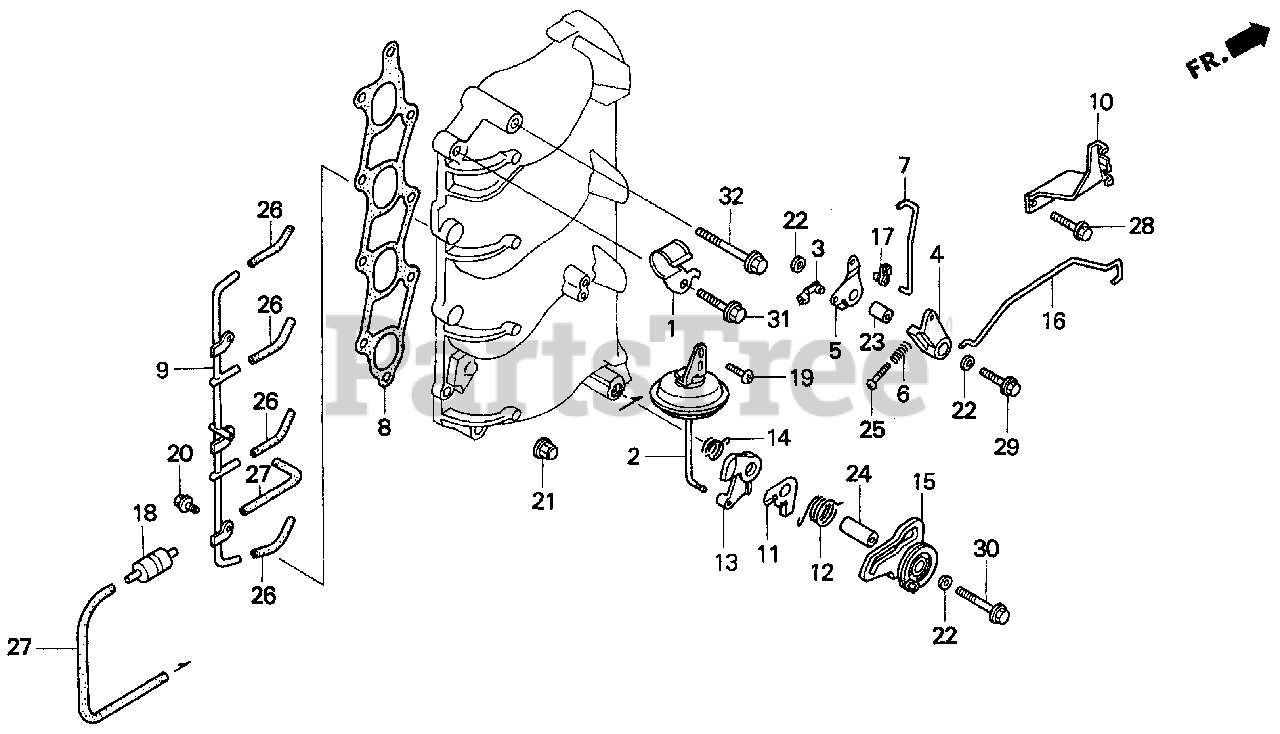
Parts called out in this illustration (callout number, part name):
1	CLAMP, TUBE
2	DIAPHRAGM ASSY.
3	JOINT, ROD
4	ARM A, CHOKE
5	ARM B, CHOKE
6	SPRING, CHOKE ARM ADJUSTING
7	ROD, CHOKE
8	GASKET, IN. MANIFOLD
9	PIPE, INSTALL
10	STAY, THROTTLE CABLE
11	PLATE, ASSIST
12	SPRING, ASSIST
13	CAM, THROTTLE OPENER
14	SPRING, OPENER CAM RETURN
15	CAM, THROTTLE
16	ROD, CHOKE KNOB
17	BUSH, LINKAGE
18	VALVE, DASHPOT SOLENOID
19	BOLT, TORX (6X14)
20	BOLT, FLANGE (5X10)
21	NUT, FLANGE CAP (8MM)
22	WASHER, PLAIN (6MM)
23	COLLAR, DISTANCE (6.5X10.5X16)
24	COLLAR (6.7X12.5X31.5)
25	SCREW, PAN (4X16)
26	BULK HOSE, FUEL (3.5X3000) (3.5X50)
27	BULK HOSE, FUEL (3.5X3000) (3.5X80)
28	BOLT, FLANGE (6X16)
29	BOLT, FLANGE (6X30)
30	BOLT, FLANGE (6X45)
31	BOLT, FLANGE (8X35)
32	BOLT, FLANGE (8X70)
